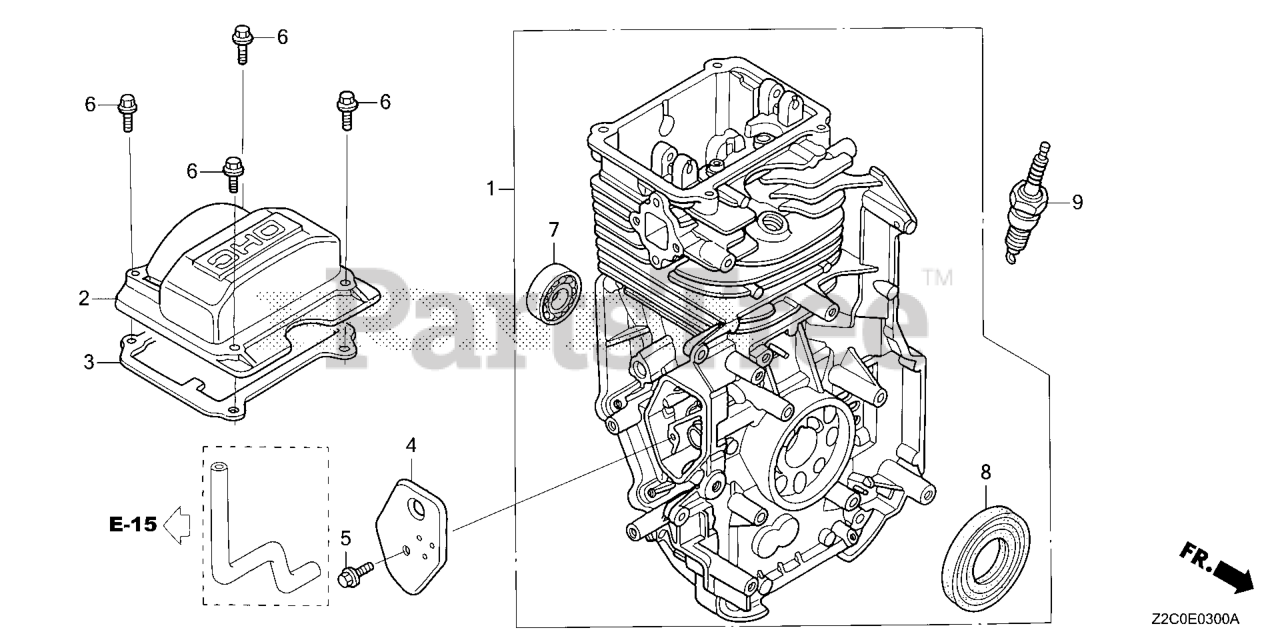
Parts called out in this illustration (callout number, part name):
1	CYLINDER ASSY.
2	COVER, CYLINDER HEAD
4	COVER, BREATHER (Honda Code 5580006). (BREATHER VALVE ASSY.)
5	BOLT, FLANGE (6X14)
6	BOLT, FLANGE (6X12) (CT200)
7	BEARING, RADIAL BALL
8	OIL SEAL (25.4X74X6)
9	SPARK PLUG (BPR6ES) (NGK)
